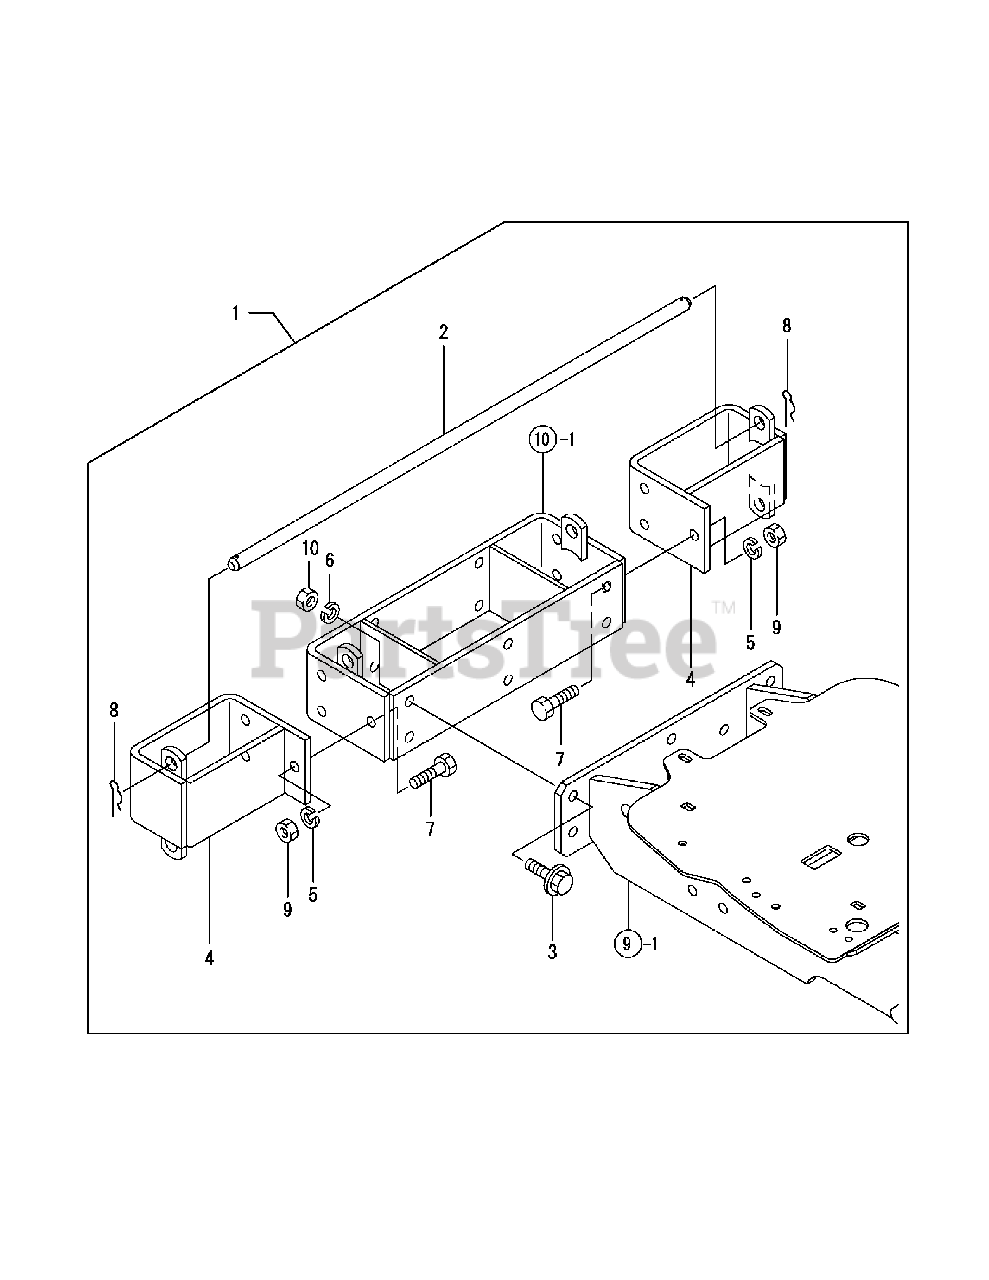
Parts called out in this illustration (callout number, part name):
1	HITCH KIT, FRONT
2	PIN,WEIGHT LOCK
4	HITCH, EXTRA FRONT
5	WASHER,LOCK 12
6	WASHER,LOCK 12
